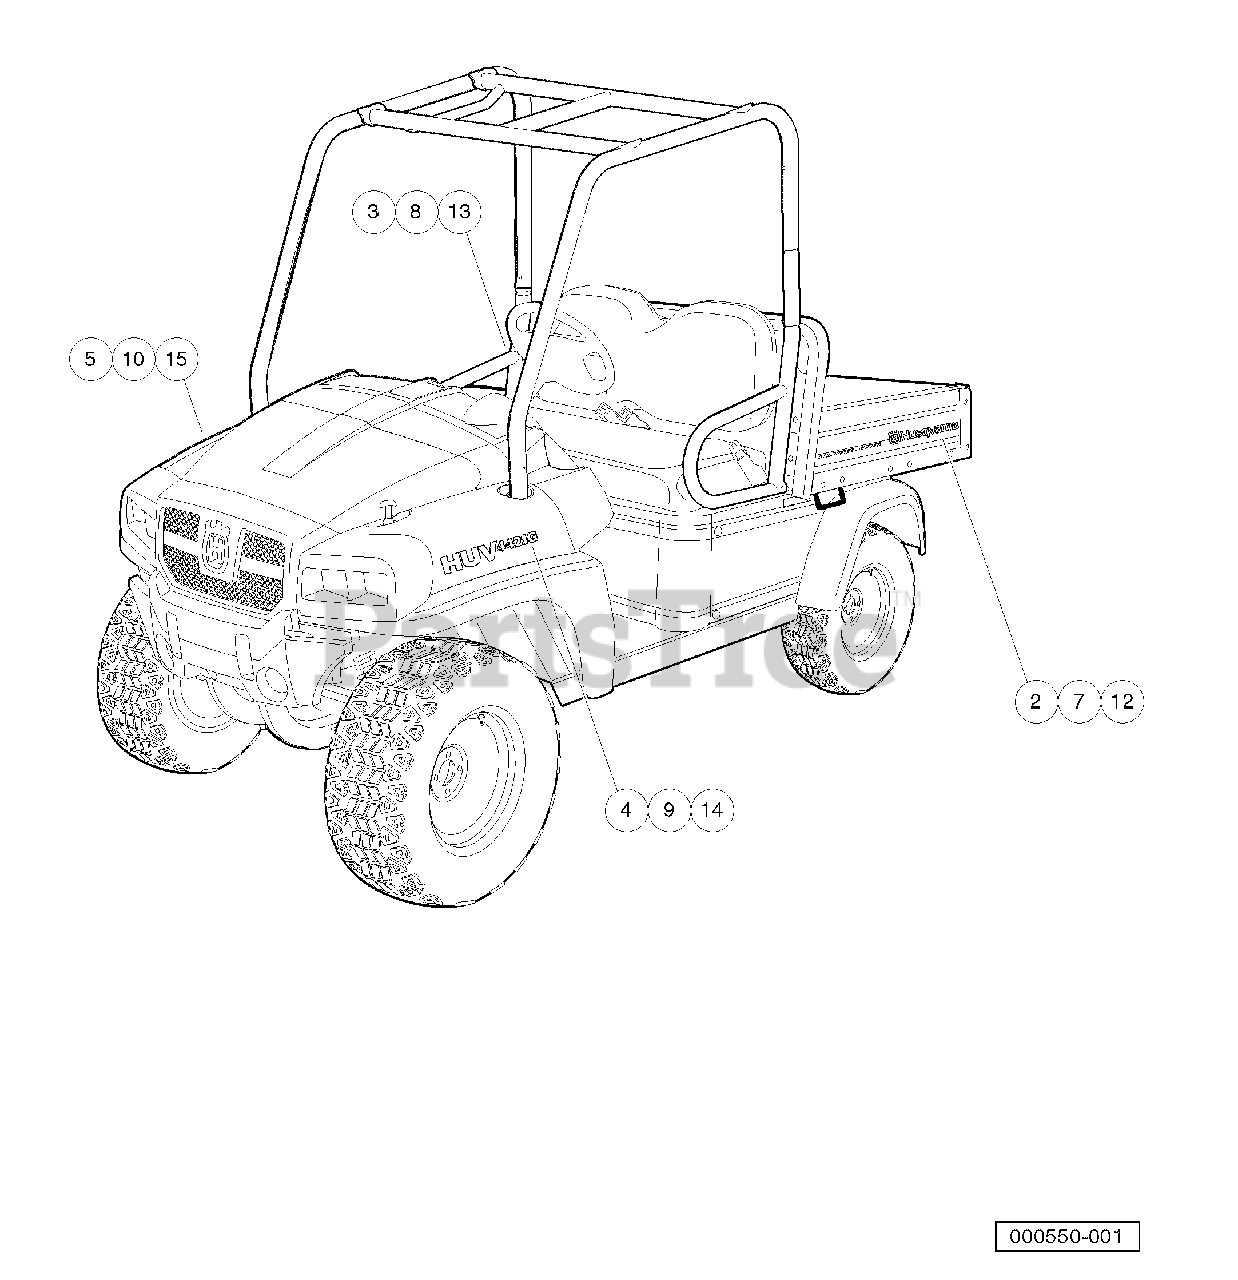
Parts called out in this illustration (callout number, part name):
1	Instl, Decal, Huv4421g,moff
2	Decal, Bed, Huv, Moff, Ds
3	Decal, Bed, Huv, Moff, Ps
4	Decal, Bct2200s, Driver-Side, Camo
5	Decal, Bct2200s, Passenger-Side, Camo
7	Decal, Bed, Huv, Orange, Ds
8	Decal, Bed, Huv, Orange, Ps
9	Decal, Huv 4421g, Orange, Ds
10	Decal, Huv 4421g, Orange, Ps
11	Instl,decal,huv4421g,olv Grn
12	Decal, Bed, Huv, Olv Grn, Ds
13	Decal, Bed, Huv, Olv Grn, Ps
14	Decal, Huv 4421g, Olv Grn, Ds
15	Decal, Huv 4421g, Olv Grn, Ps
